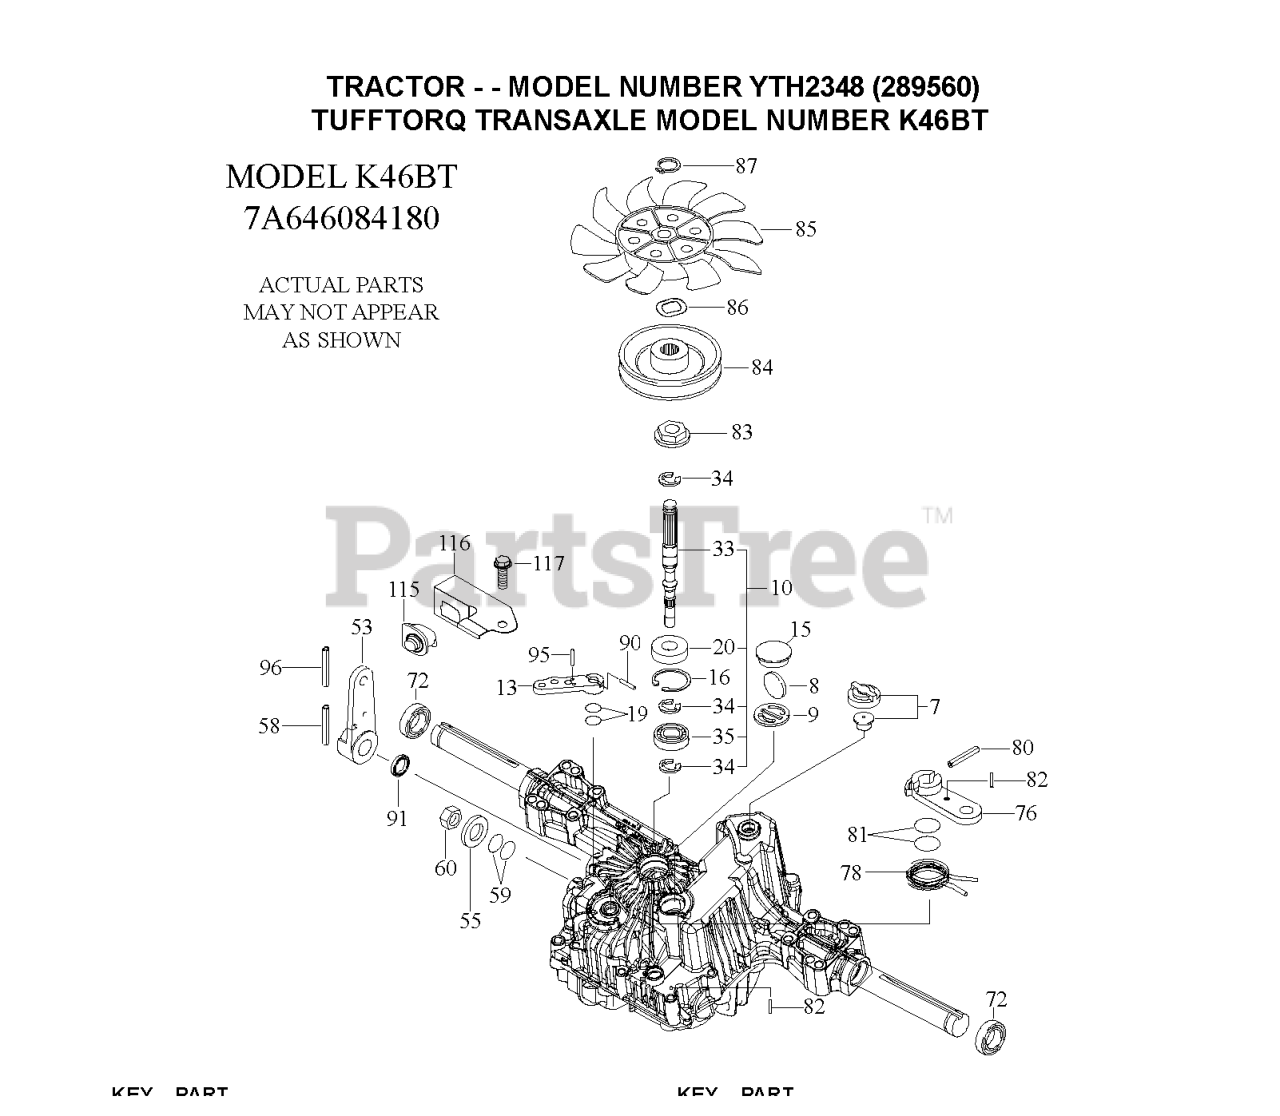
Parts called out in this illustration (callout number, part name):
7	VENT
8	MAGNET
9	Magnet Holder
10	Pump Shaft/Bearing Kit
13	LEVER.BYPASS.1A632029520
15	Sealing Cap 30
16	Snap Ring C 35
19	O-RING
20	SEAL
33	Pump Shaft (Standard)
35	Bearing 6202c3
53	LEVER
58	Roll Pin 6 x 40
59	O-Ring 1a P14
72	SEAL.19, 19216334280
76	Brake Lever
78	SPRING
80	SPRING
81	O-RING
82	PEN
83	SPINE COLLAR
84	PULLEY
85	FAN.BLACK.1A646083070
86	WASHER
87	RING
90	PEN
91	SEAL.OIL.16
95	PIN.SPR.3.0A
96	PEN
115	Switch 6440-11 Delta
116	Switch Bracket
117	Tapping Screw 8 x 20
